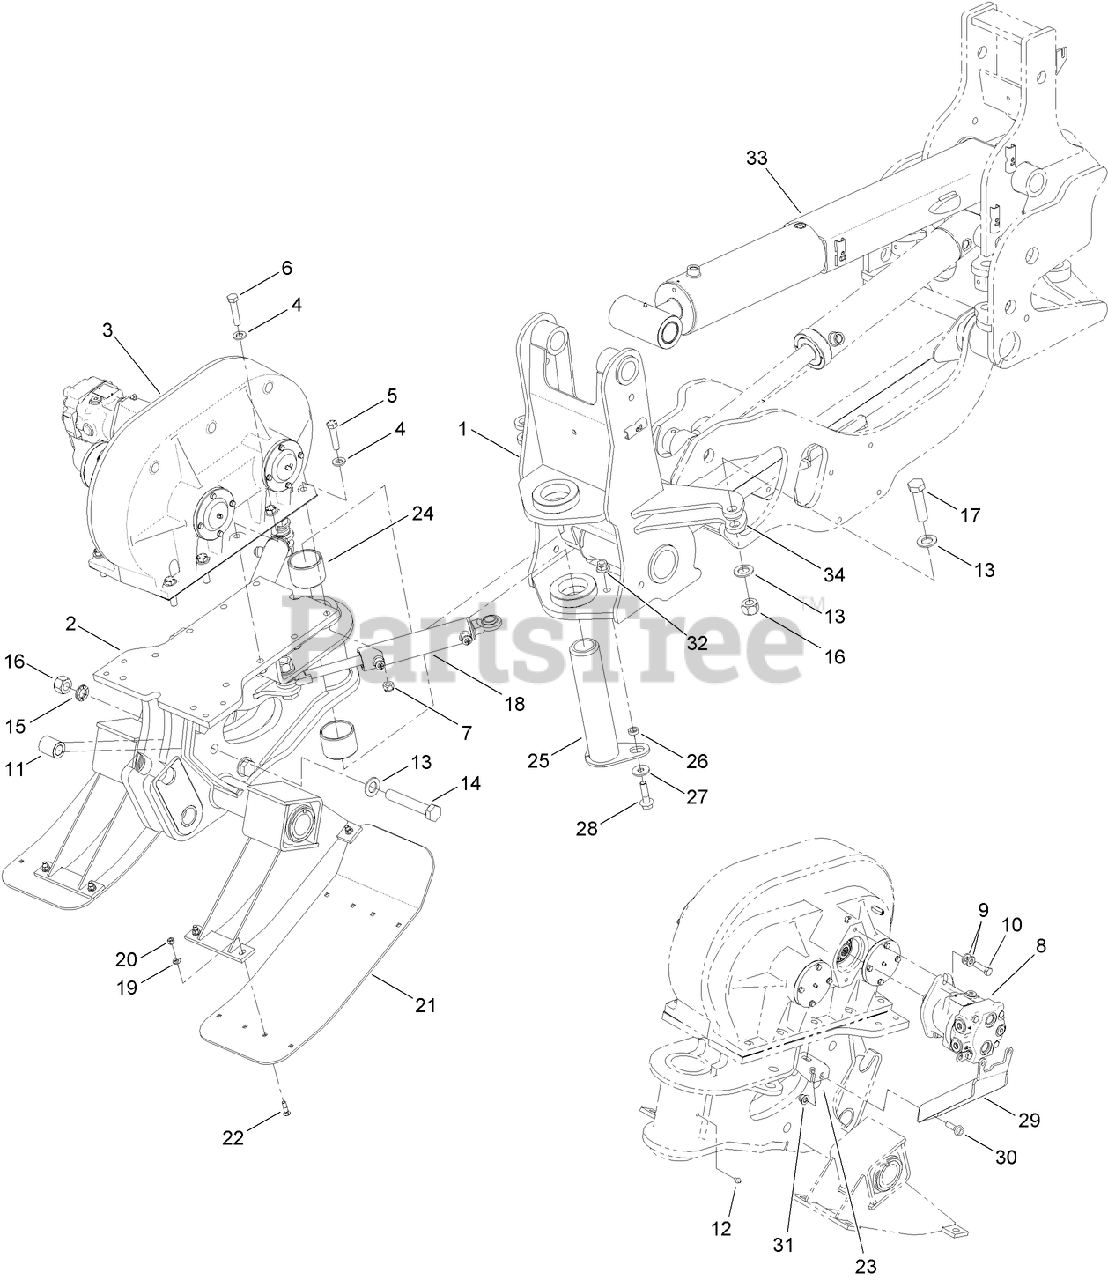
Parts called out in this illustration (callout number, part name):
1	FRAME-TRAIL
2	MOUNT-BLADE
3	SHAKER BOX ASM
4	WASHER-FLAT
5	SCREW-HH
6	SCREW-HH
7	NUT-LOCK, HEX
8	HYD MOTOR ASM
10	SCREW-HH
11	TUBE-SPACER, SOD CUTTER
12	FITTING-GREASE
14	BOLT-HH
15	WASHER-LOCK
17	BOLT-HH
18	HYD CYLINDER ASM
19	WASHER-FLAT
20	NUT-HEX
21	PLATE-WEAR, PLOW SHOE
22	SCREW-PLOW
23	PLATE-MOTOR SUPPORT, LOWER
24	BUSHING
25	PIN-FLAGGED
26	SPACER-PIN
27	WASHER-FLAT
28	SCREW-HHF
29	PLATE-MOTOR SUPPORT, UPPER
31	NUT-HHF, LOCK
32	NUT-HHF
33	HYD CYLINDER ASM
34	SPACER
